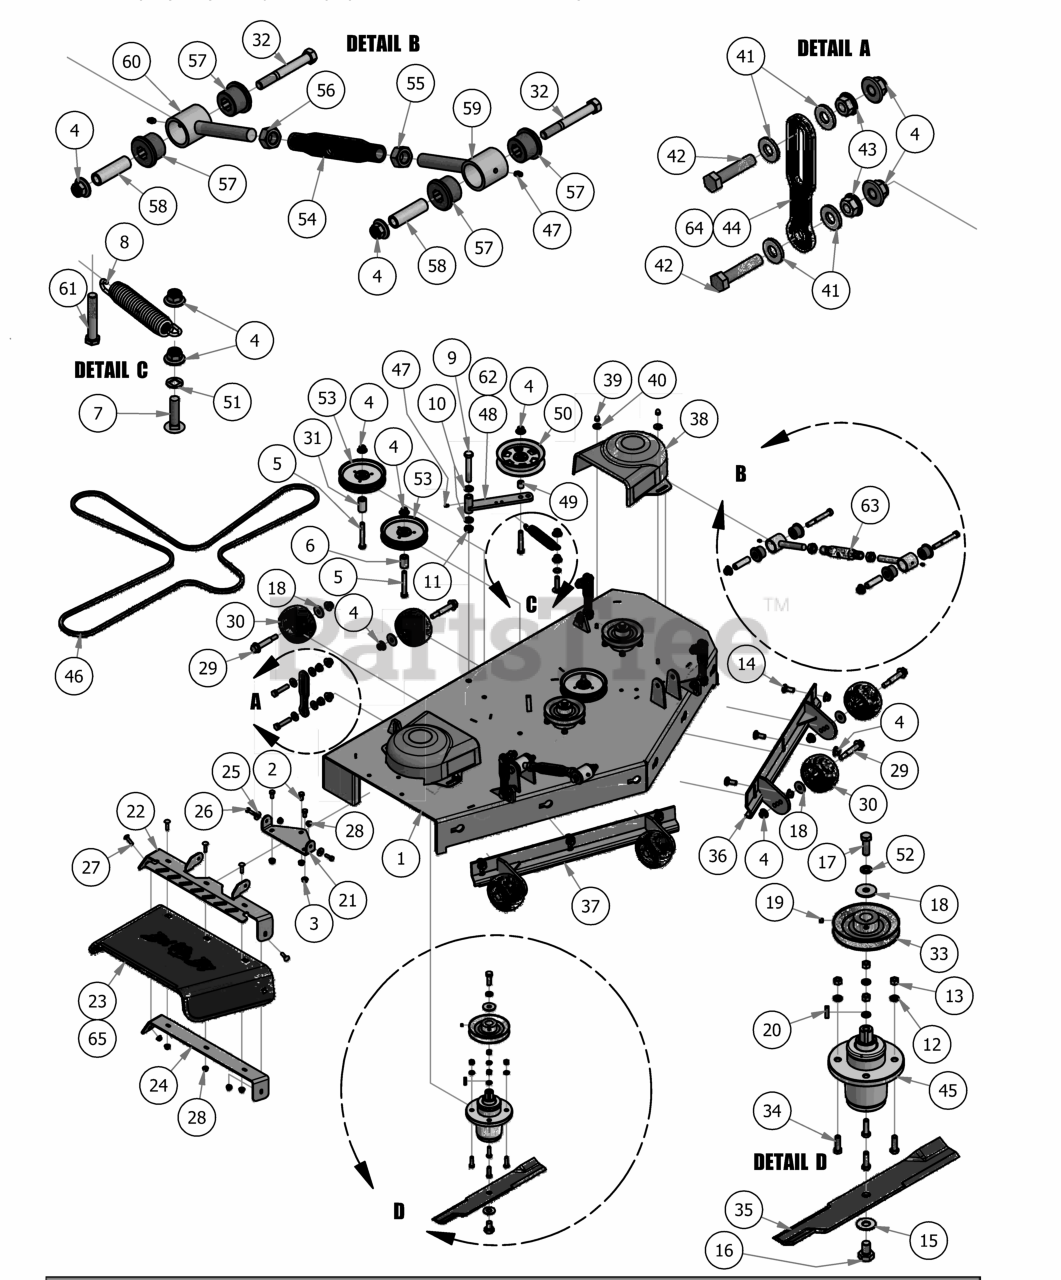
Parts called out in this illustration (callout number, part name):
1	2015 54" Deck
2	3/8" x 3/4" Hex Bolt
3	3/8" Flange Nut
4	1/2-13 Nylon Flange Nut
5	1/2 x 3 1/2 Flange Bolt Grade 8
6	Idler Pulley Standoff
7	1/2 x 2" Carriage Bolt
8	Deck Idler Spring
9	5/8" x 4" Hex Bolt
10	.630 ID Plastic Washer
11	5/8-11 Nylon Insert Jam Half Nut
12	3/8 Lockwasher Zinc
13	3/8-16 Hex Nuts Zinc
14	1/2" x 1 1/4 Carriage Bolt
15	5/8'' Flat Washer
16	5/8" x 1 1/2" Grade 8 Hex Bolt (Fine)
17	1/2"-20 x 1 1/2 - Grade 5 Fine Thread Bolt
18	1/2" Belleville Washer
19	5/16 Set Screw
20	1/4" x 1" Key
21	Discharge Chute Hanger (deck mounted)
22	60" Discharge Chute Upper Hanger
23	Rubber Discharge Chute
24	60" Discharge Lower Bracket
25	.360 ID Plastic Washer
26	5/16" x 1" Bolt
27	5/16" x 1 1/4" Carriage Bolt
28	5/16" Nylock Flange Nut Zinc
29	Deck Wheel Bolt
30	Anti-Scalp Roller
31	1 3/4" Pulley Spacer
32	1/2" x 4" Bolt (Grade 8)
33	5.25" Deck Spindle Pulley
34	3/8" x 1 1/4" Hex Bolt
35	54" Deck Fusion Blade For Outlaw
36	54 Deck Adustable Front (Left)
37	54 Deck Adustable Front (Right)
38	Pulley Cover
39	Acorn nut-pulley Cover
40	.360 ID Plastic Washer-Black
41	.505 Nylon Spacer
42	1/2-13X 2-1/4 GR Hex Bolts
43	1/2" Flange Nut
44	Deck_Hanging_Tab
45	OUTLAW SPINDLE ASSEMBLY
46	60" ZT Deck Belt
47	1/4" Press in Grease Fitting
48	Deck Idler
49	Spacer 3/4 OD x 1/2 ID x 3\4 Length
50	5" Idler Pully
51	.517 Square Hole Round Washer
52	1/2" Lock Washer
53	5-3/4 Idler Pulley-Capitol Stampings
54	2015 Outlaw Toplink Body
55	3/4-10 Left-Handed Hex Nuts Zinc
56	3/4-10 Hex Nuts Zinc
59	Turn Left-Handed
60	Right-Handed End
61	1/2-13 x GR 5 Hex Bolt Zinc
62	Deck Idler Assembly - Includes parts:4, 47, 48, 49, 50, 61
63	Turnbuckle Assembly
64	Outlaw Deck Hanger Assembly - Includes Parts:4,41,42,43,44
65	Chute Assembly - Includes Parts:22,23,24,27,28
